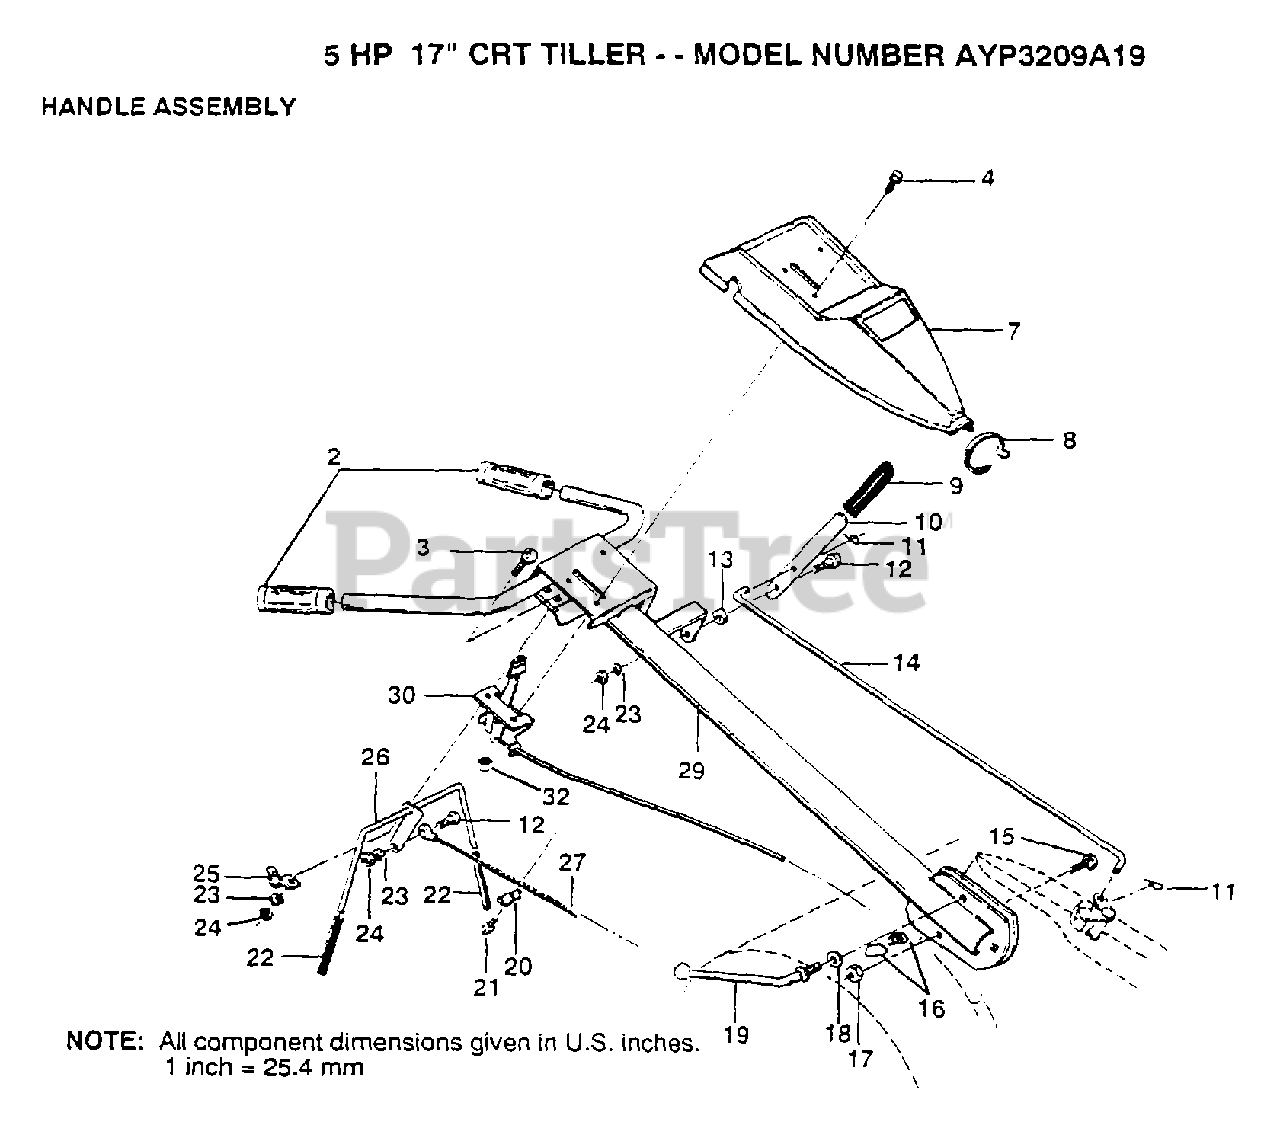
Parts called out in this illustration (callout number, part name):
3	BOLT
4	SCREW
7	"PANEL,CONT TI"
8	TIE CABLE CRT
9	GRIP T
10	SHIFT HANDLE CRT
11	RETAINER M
12	SHOULDER BOLT ST
13	GROMMET CRT
14	SHIFT ROD CRT
15	BOLT D
16	LOCK CRT
18	WASHER CRT
19	LEVER LOCK CRT
20	CONDIUT CLIP T
22	GRIP BAR CRT
23	LOCKWASHER
26	"ASSY CONTROL, BAR"
27	CABLE.CLUTCH.CRT
30	"CONT,THROTTLE"
